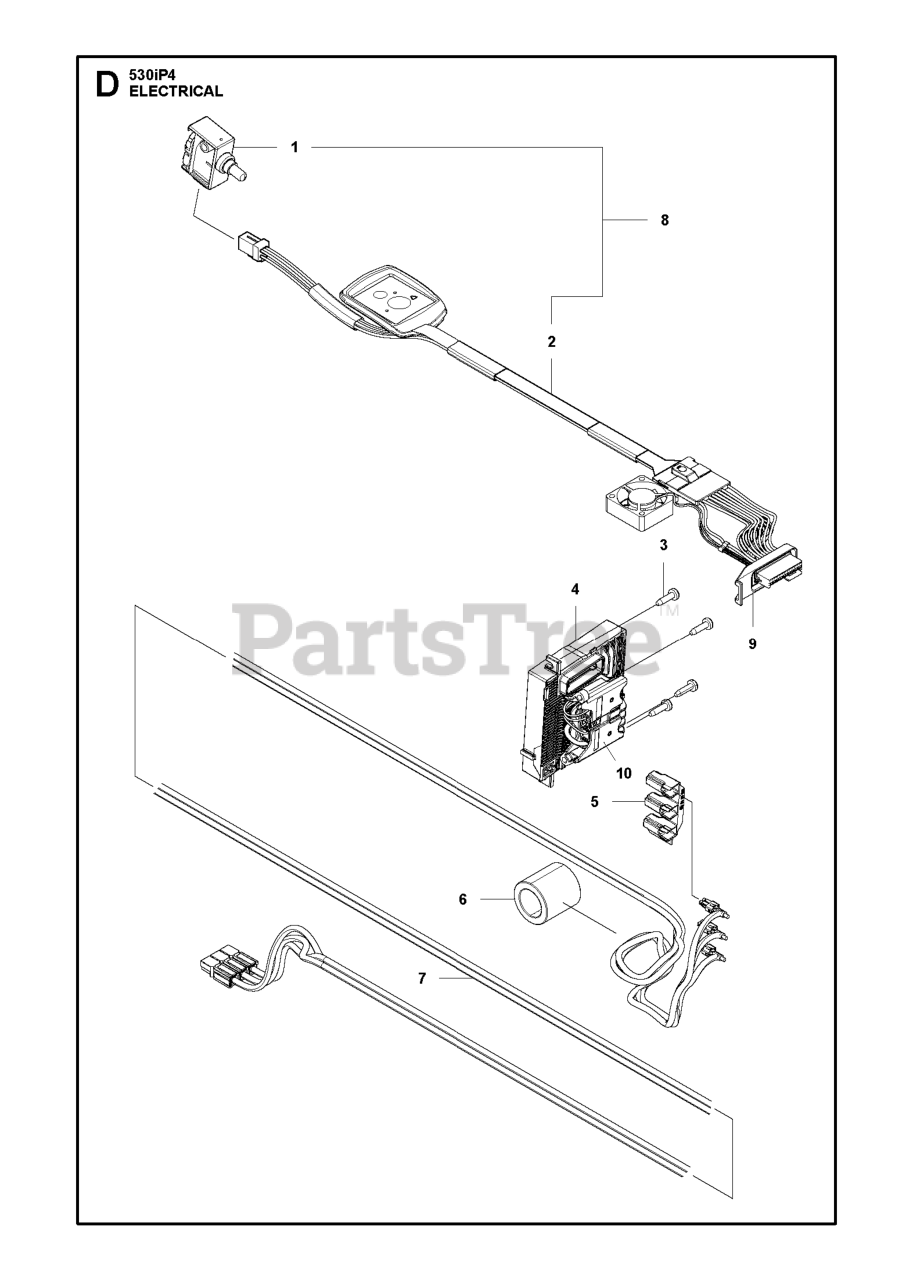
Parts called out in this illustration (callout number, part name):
1	TRIGGER SWITCH IPX4
2	WIRING ASSY POLE SAW MAIN
4	CONTROL UNIT BLDC - 536LIHE3
5	HOUSING POWER TIMER, 3-POLE
6	FERRITE CORE
7	WIRING ASSY MOTOR CABLES POLES
8	SWITCH KIT BATTERY POLESAW 536
10	CONNECTOR BATTERY
